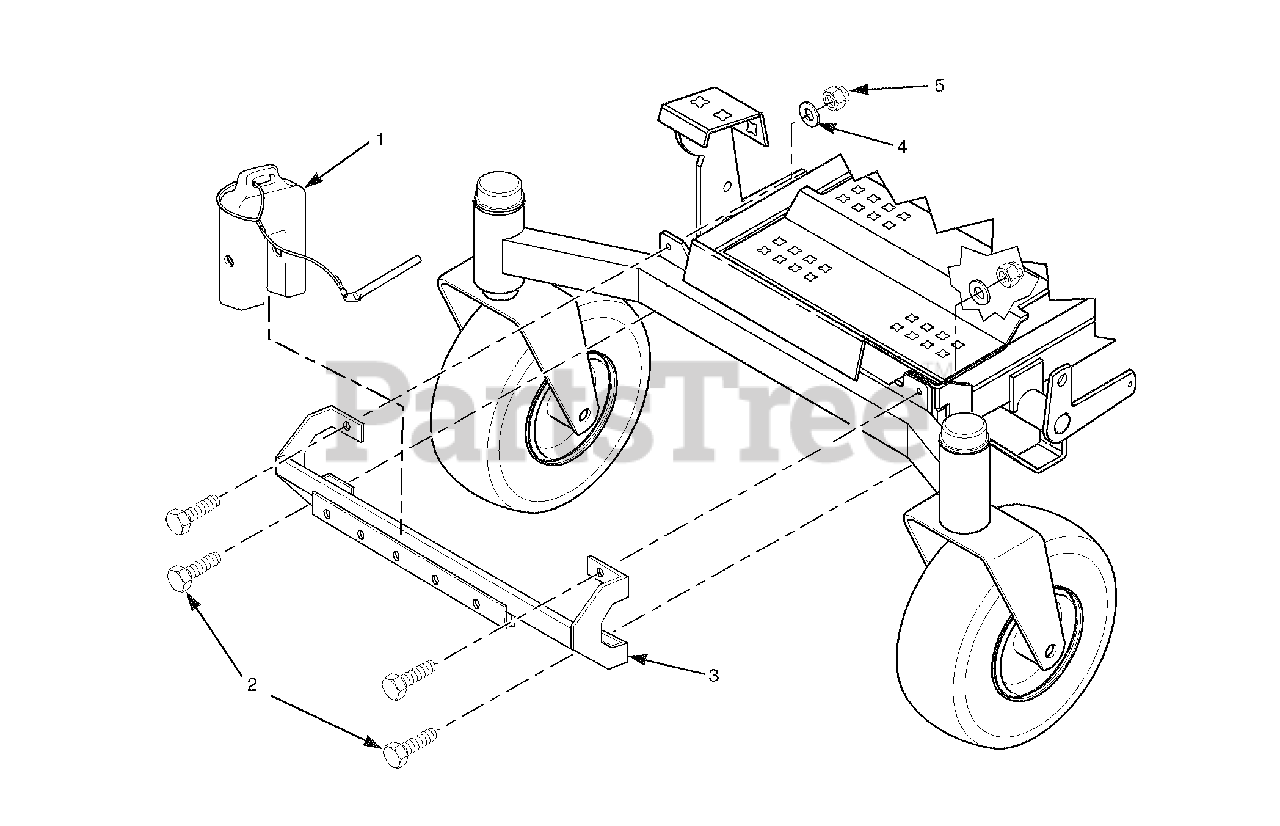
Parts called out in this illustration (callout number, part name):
1	Weight Assembly
2	Bolt, Hex Head 7/16-14 x 1-3/4"
3	Suppor t Weldment, Weights
4	Flatwasher, 7/16-.500 x 1-1/4"
5	Nut, Elastic Stop 7/16-14
